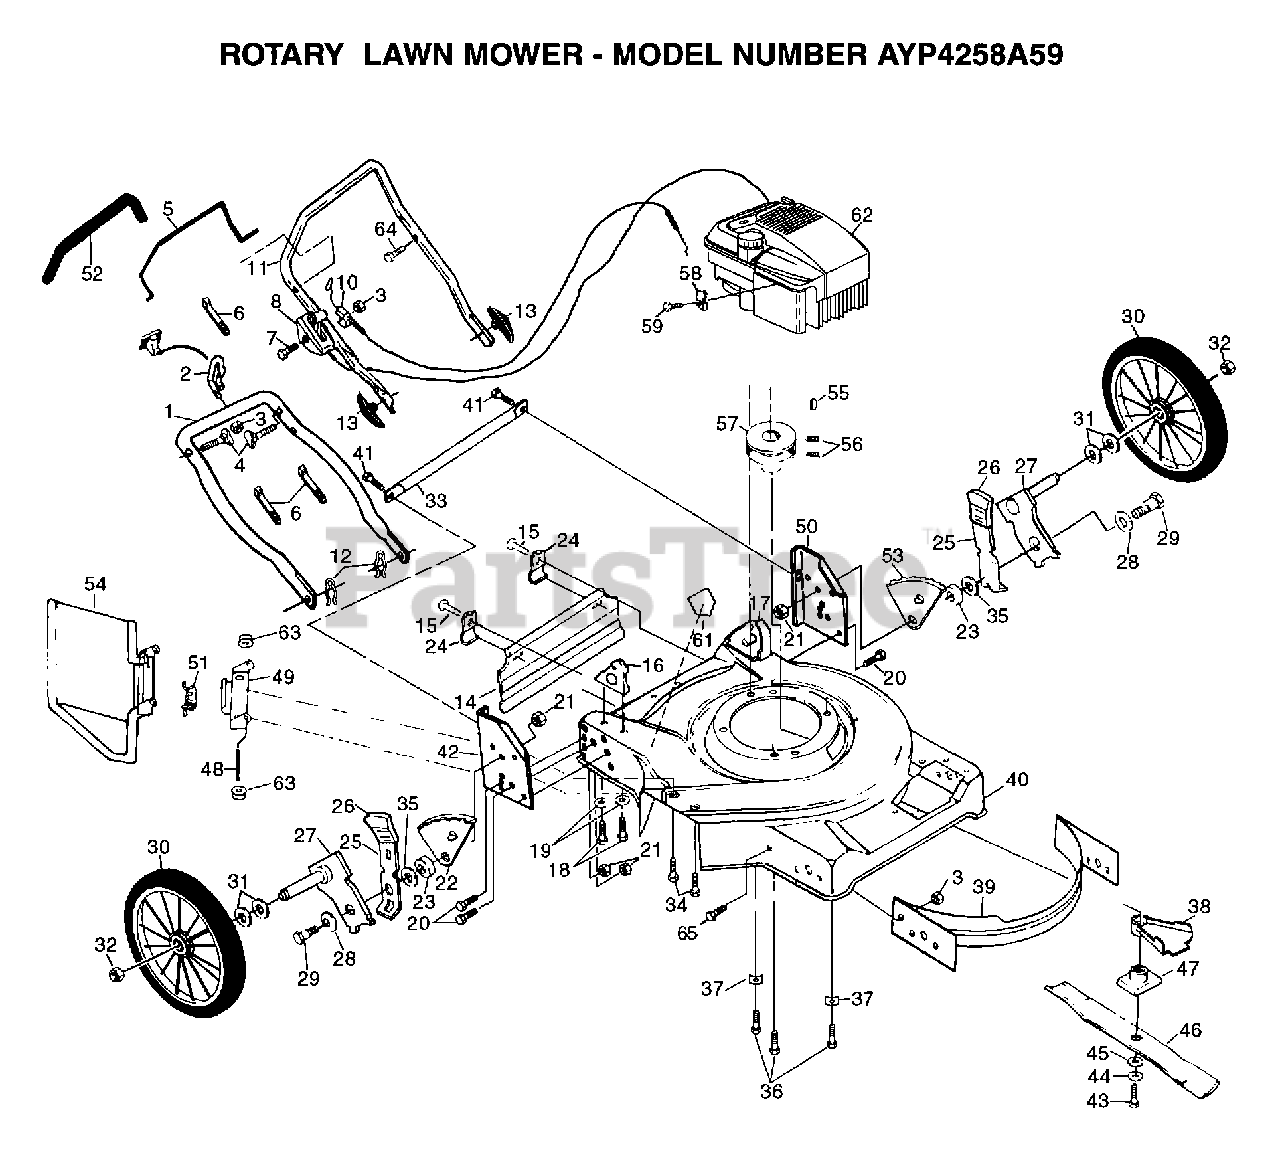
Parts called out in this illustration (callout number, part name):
2	ROPER GUIDE PM
4	BOLT.HANDLE.LM
5	CONTROL BAR
7	SCREW.HXHD.WASH.
8	"CONTROL, THROTTLE"
10	"CABLE,ENG ZONE CO"
12	HAIRPIN COTTER
13	KNOB HANDLE
14	SKIRT.REAR.22SD.
15	TAPPING SCREW
18	SCREW
19	STEEL WASHER
21	LOCKNUT PM
22	BRACKET ASM LF/RR
24	"BRKT,DEFL PM"
25	SELECTOR SPRING
29	BOLT SHLD 3/8-16
30	ASM WHL & TIRE
31	WAVE WASHER
32	HEX FLANGE LOCKNT
33	ROD SUPPORT
34	SCREW
35	WASHER PM
36	SCREW
39	BAFFLE FRONT 22SD
40	KIT.HSG.22SD.FWGD
41	SCREW
42	WHL SUPT BRKT RH
43	SCREW
44	LOCKWASHER
45	"WASHER,HARDEN"
46	"BLADE.MULCH.22"""
47	ADAPTOR.BLADE.LM
48	"ROD,HINGE "
49	"BRKT,HSG"
51	"SPRING,TORSION"
53	BRACKET ADJ LR/RF
55	HI PRO KEY PM
56	SCREW
57	ENGINE.PULLEY.FWG
58	CABLE CLAMP
59	SCREW PM
61	DECAL-DANGER PM
63	PUSH ON SPEED NUT
64	"SCREW,PAN HD"
65	SCREW
